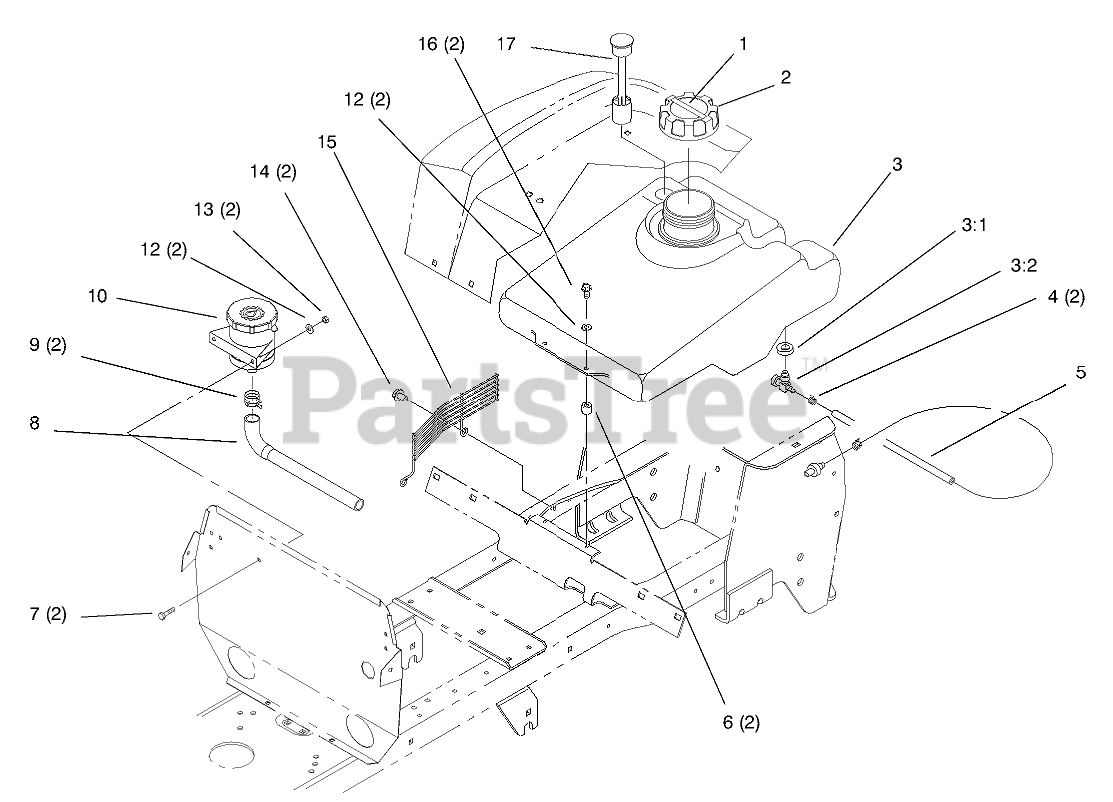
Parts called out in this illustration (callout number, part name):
2	GAS CAP ASM
3	TANK-FUEL
4	CLAMP-HOSE
5	HOSE - FUEL LINE TWIN
6	SPACER - FUEL TANK
7	SCREW-HH
8	HOSE - HYDRO
9	CLAMP-HOSE
10	ASS'Y-RESERVOIR
12	WASHER-FLAT
13	NUT-LOCK, NI
14	SCREW-HWHTF
15	GUARD - FAN
16	SCREW-HH
17	SENSOR-FUEL, LOW
17:1	SEAL - FUEL SENDER
17:2	Sensor-Fuel Level
